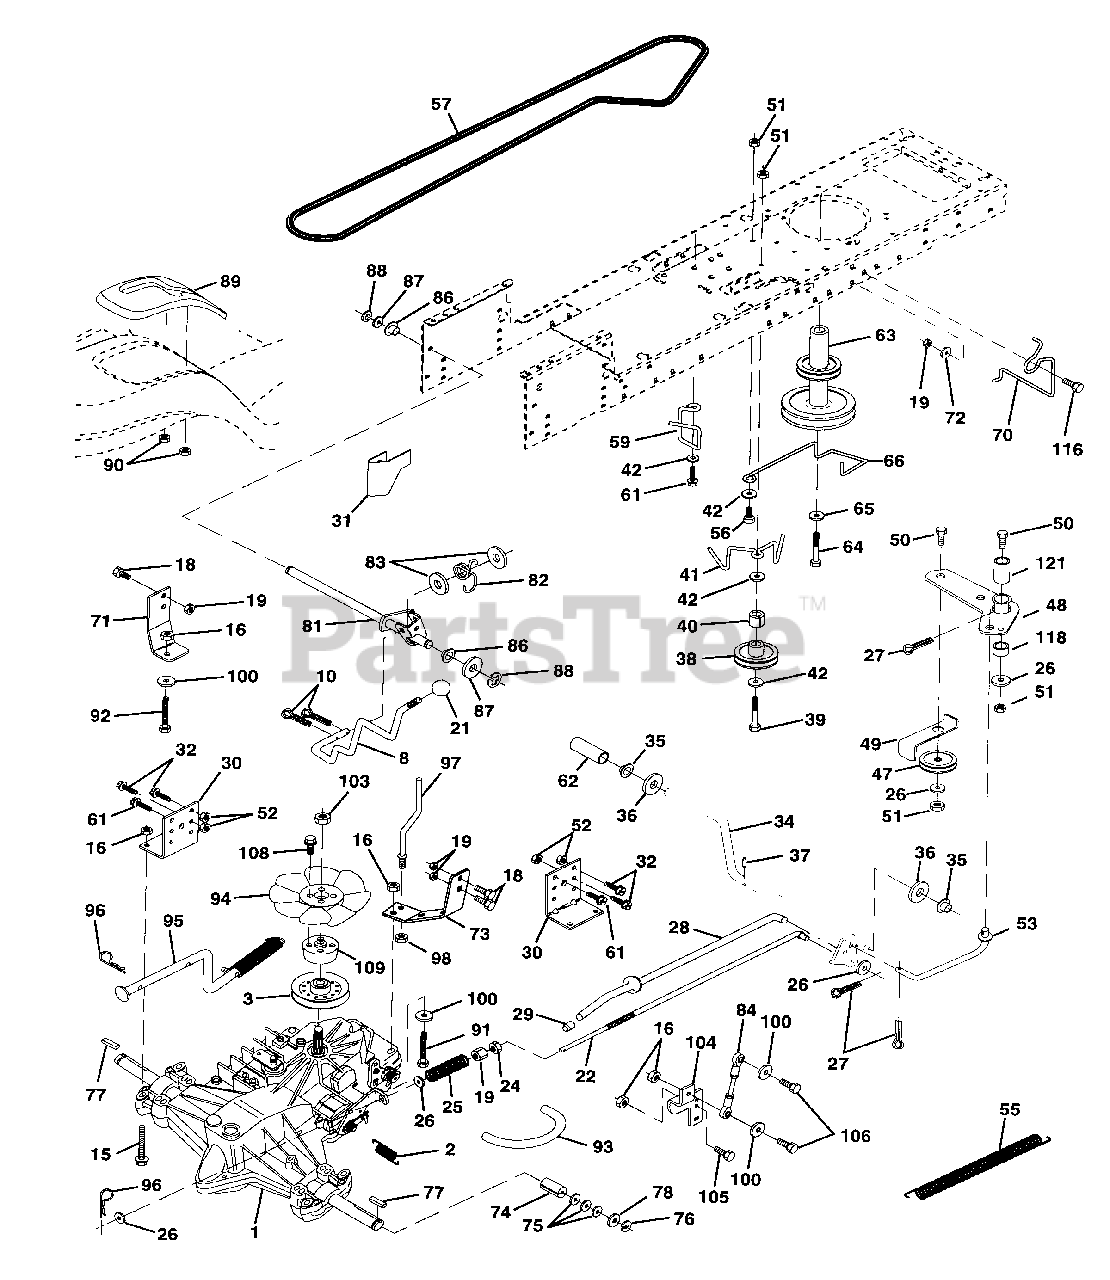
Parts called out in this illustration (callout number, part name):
1	Transaxle Assembly
2	Spring, Return, Brake
3	Pulley, Transaxle
8	Rod Shift Fender STLT
10	Pin Cotter 1/8 x 1 CAD
15	Bolt Hex Flghd 5/16-18 Gr 5
16	Nut Lock Hex W/Ins 5/16-18 Unc P
18	Bolt Fin Hex 3/8-16 Unc x 1 Gr. 5
19	Nut Lock Hex W/Wsh 3/8-16 Unc
21	Knob 1/2-13
22	Rod, Brake Hydro
24	Nut
25	Spring, Brake Rod
26	Washer
27	Pin Cotter 1/8 x 3/4 CAD.
28	Rod, Parking Brake
29	Cap, Parking Brake
30	Bracket, Transaxle
31	Keeper Belt Lh
32	Bolt Hex Hd 5/16-18 Unc x 3/4
34	Shaft, Foot Pedal
35	Bearing, Nylon
37	Pin, Roll
38	Pulley, Idler, Flat
40	Spacer, Split
41	Keeper, Belt Retainer
42	Washer 13/32 x 13/16 x 12 Gauge
47	Pulley, Idler, V-Groove
48	Bellcrank Assembly
49	Retainer, Belt
50	Bolt
51	Nut Crownlock 3/8-16
52	Nut Crownlock 5/16-18
53	Link, Clutch
55	Spring, Return, Clutch
56	Bolt Fin Hex 3/8-16 Unc x 1-1/4
57	V-Belt, Ground Drive
59	Keeper, Center Span
61	Screw Thdrol. 3/8-16 x 3/4 Ty. TT
62	Cover, Pedal
63	Pulley, Engine
64	Bolt, Hex
65	Washer
66	Keeper, Belt Engine Flproof
70	Keeper Belt Engine
71	Strap Torque Lh Hydro 500 18"
72	Washer 13/32 x 1-1/4 x 12 Gauge
73	Strap Torque Rh Hydro 500 18"
74	Spacer,
75	Washer 25/32 x 1-1/4 x 16 Gauge
77	Key, Square
78	Washer 25/32 x 1-5/8 x 16 Gauge
81	Shaft Asm. Cross Hydro 500
82	Spring Torsion T/A
83	Washer 17/32 x 3/4 x 16 Ga.
84	Rod, Tie Hydro Sph Ball 500
86	Bushing Rod Strig. 629/632 ID
87	Washer 21/32 x 1-1/4 x 16 Ga.
88	Ring Klip #5304-62
89	Console, Shift Hydro STLT
90	Nut Self-Thd Wsh-Hd 1/4 Zinc
91	Bolt Fin Hex 5/16-18 x 2-1/4
92	Bolt Fin Hex 5/6-18 Unc x 1-1/2
93	Line Fuel Hydro 4"
94	Fan, Hydro 7"
95	Control Asm. Bypass Hydro
96	Retainer Spring 1" Zinc/Cad
97	Keeper Belt Rh Hydro 500
98	Nut Keps Hex 3/8-16 Unc
100	Washer 11/32 x 3/4 x 16 Ga.
103	Nut, Hex Jam Toplock 1/2-20 Unf
104	Arm, Control Pump
105	Screw Cap Hex 5/16 x 18 x 1
106	Bolt Fin Hex 5/16-18 Unc x 1-1/4
108	Screw Hex Wh Hd #10-24 x 1-5/8
109	Adaptor Fan/Hydro Lt Hyd Alum
116	Bolt, RDHD SQ Neck 3/8-16 x 1.25
118	Spacer Bellcrank
121	Nyliner Clutching STL
